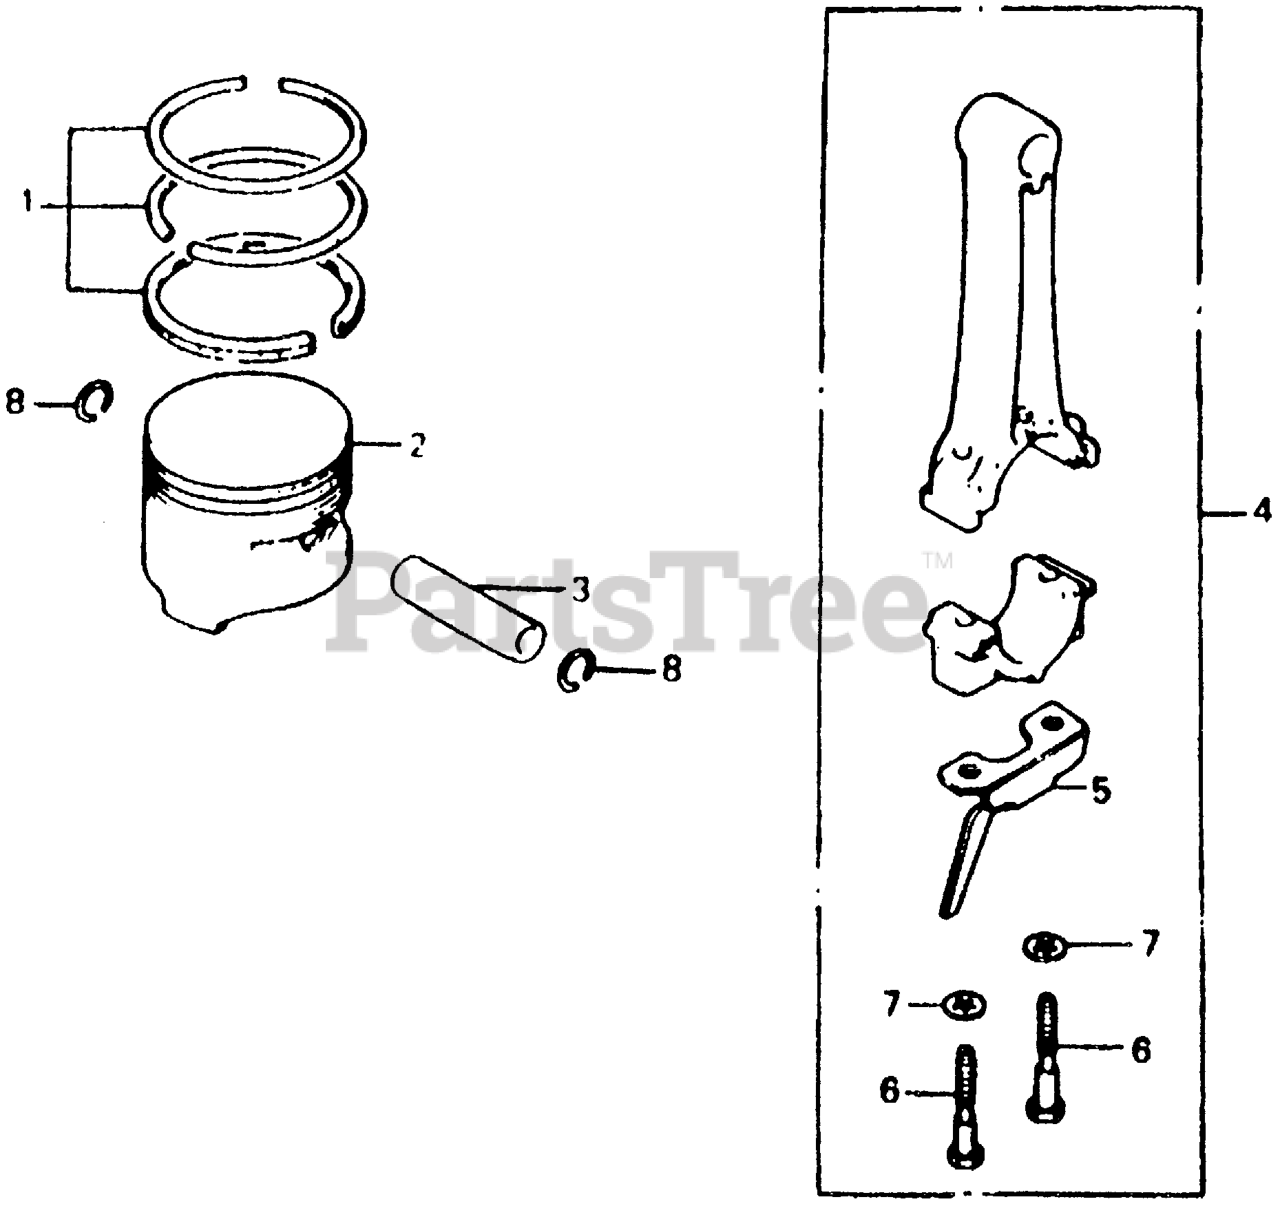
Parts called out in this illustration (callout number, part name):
1	RING SET, PISTON
1	RING SET, PISTON (STD)
1	RING SET, PISTON (OS 0.25)
1	RING SET, PISTON (OS 0.50)
1	RING SET, PISTON (0.75)
1	RING SET (0.75)
2	PISTON (STD)
2	PISTON (OS 0.25)
2	PISTON (OS 0.50)
2	PISTON (0.75)
3	PIN, PISTON
4	ROD ASSY., CONNECTING
4	ROD ASSY., CONNECTING (UNDER SIZE)
5	DIPPER, CONNECTING ROD
6	BOLT, CONNECTING ROD (7MM)
7	WASHER, LOCK (7MM)
8	CLIP, PISTON PIN (16MM)
